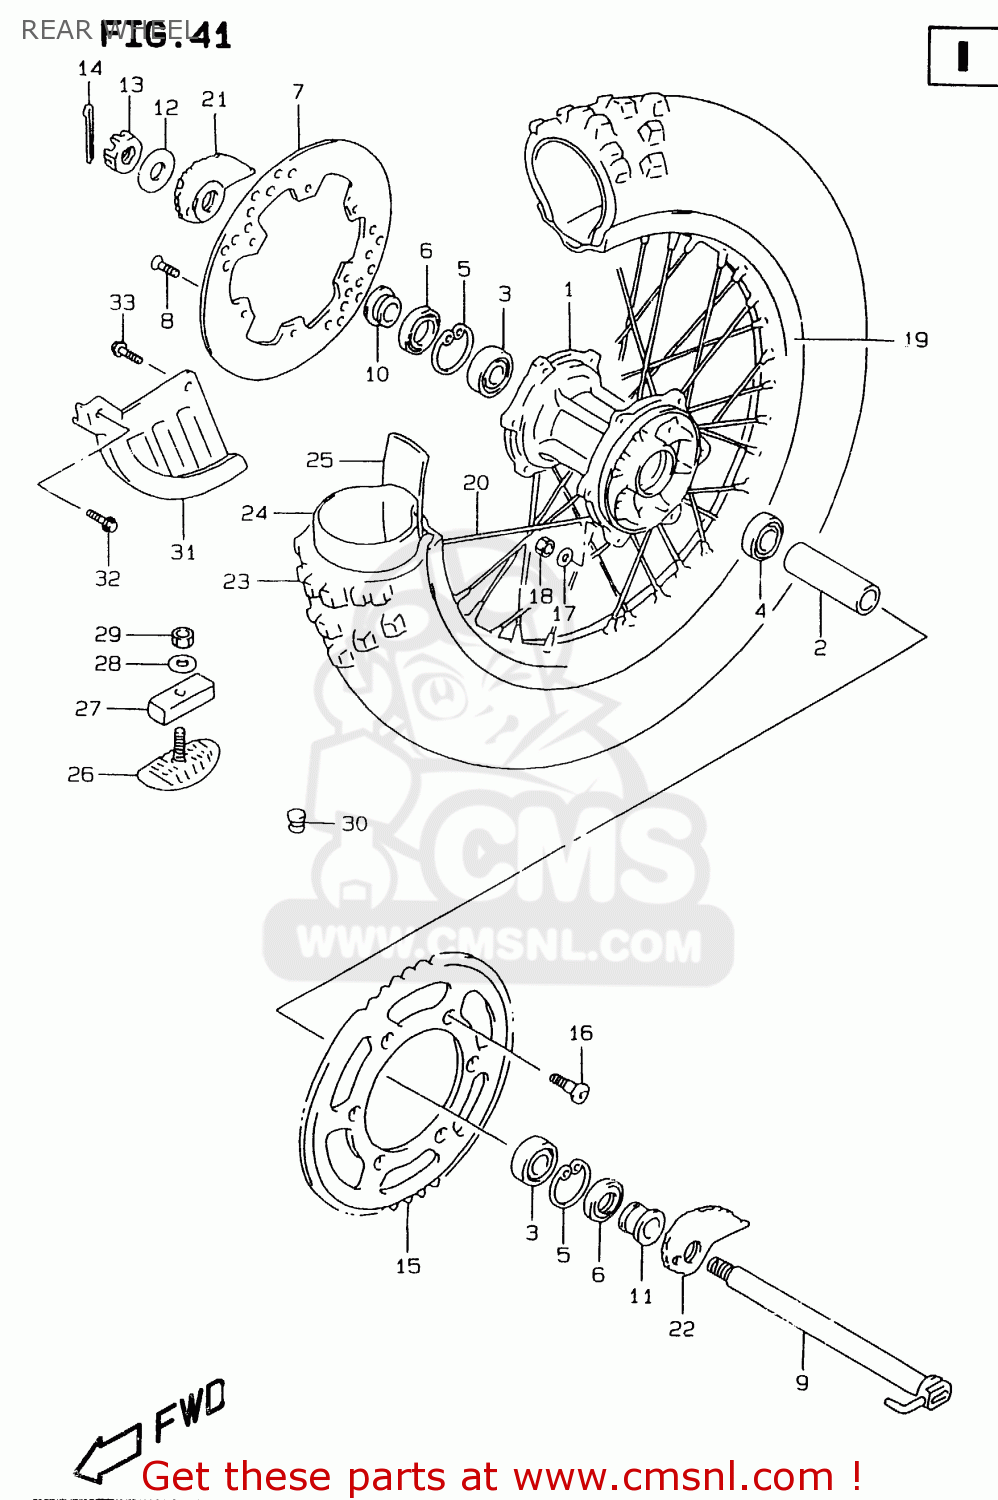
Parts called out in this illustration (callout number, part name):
1	HUB,RR
2	SPACER,RR HUB BEARING
3	BEARING WHEEL REAR(20X47X14)
4	BALL BEARING
5	CIRCLIP,14MM
6	SEAL,OIL(26X47X5)
7	DISC,RR BRAKE
8	SCREW
9	AXLE,RR
10	SPACER,RR AXLE,R
11	SPACER,RR AXLE,L
12	WASHER(19X32X3.2)
13	NUT
14	PIN,COTTER
15	SPROCKET,RR(NT:50)
16	SCREW(8X33.5)
17	WASHER
18	NUT
19	RIM,REAR WHEEL (2.15X18)(A
20	SPOKE ASSY,RR WHEEL
21	ADJUSTER,CHAIN,R
22	ADJUSTER,CHAIN,L
23	TIRE,REAR 110/100-18
24	TUBE ASSEMBLY,WHEEL,INNER
25	PROTECTOR,INNER TUBE
26	STOPPER,BEAD(2.15)
27	CUSHION,BEAD STOPPER
28	WASHER
29	NUT
30	CAP(OD:12)
31	COVER SET,RR BRAKE DISC
32	BOLT
33	BOLT
